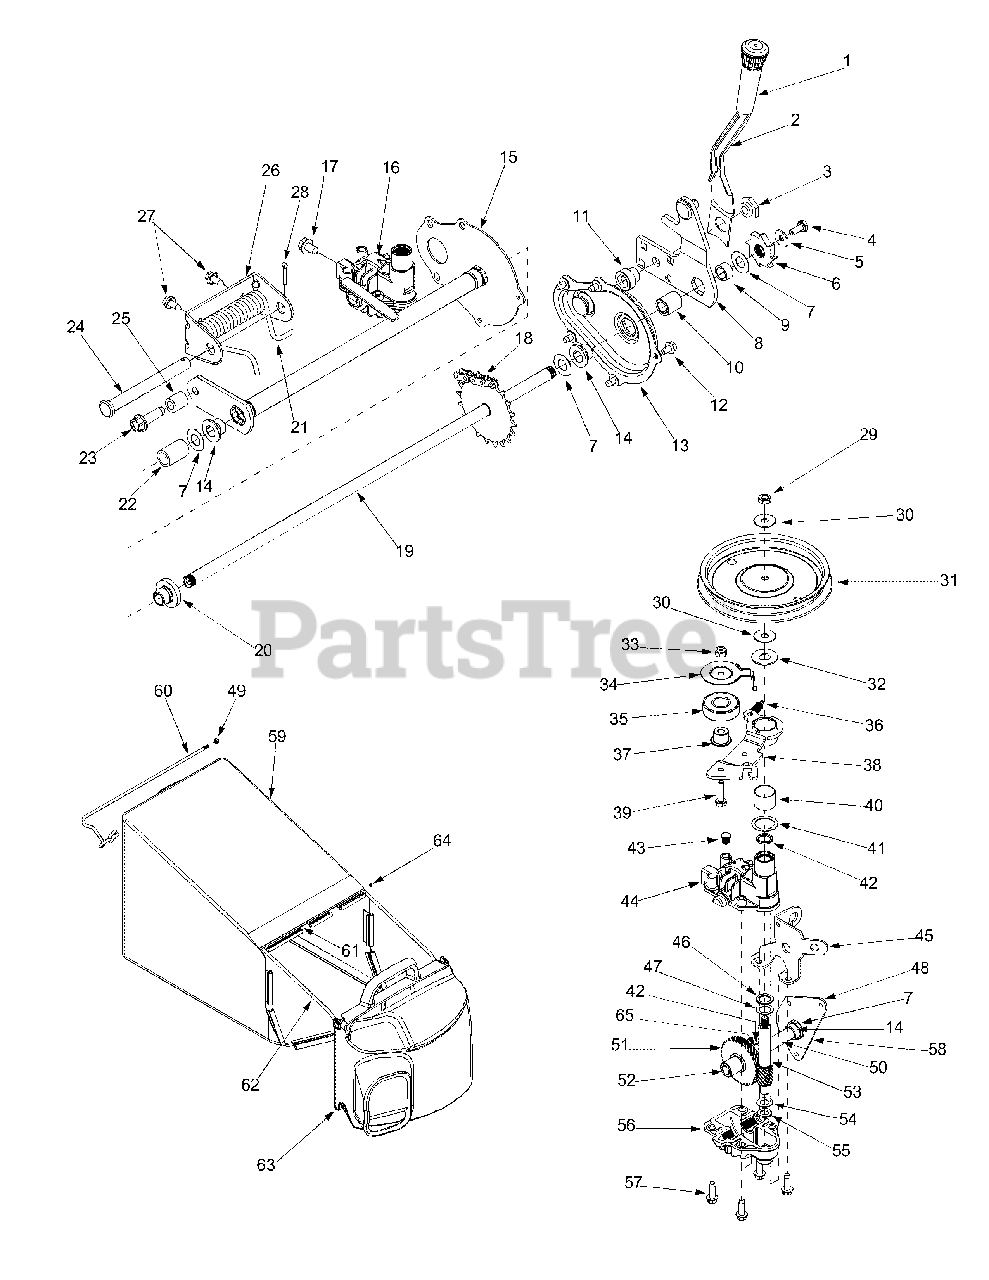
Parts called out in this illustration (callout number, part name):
2	Spring Lever
3	Shoulder Nut.825 x.165 Lg.
4	Cap Screw 1/4-20 x.620
5	Bell Washer.285 ID x.75 OD
6	Wheel Rachet
7	Flat Washer.508 ID x 1.0 OD
8	Pivot Arm Assembly
9	Spacer.510 ID x.70 OD
10	Sleeve Bearing.504 ID x.830 OD
11	Shoulder
12	Tap Screw 1/4-20 x.375
13	Chain Cover Assembly
14	Flange Bearing.506 ID x.590 Lg
15	Transmission Axle Assembly
16	Transmission Assembly
17	Hex Screw 5/16-18
18	Chain
19	Rear Axle Assembly
20	Flange Bearing.506 ID x.715 Lg
21	Torsion Spring
22	Spacer.550 ID x.750 OD
23	Screw 3/8-16 x.25
24	Clevis Pin.50 Dia x 4.82 Lg.
25	Spacer.385 ID x.624 OD
26	Height Adjustment Spring Bracket
27	Screw 1/4-20 x.625
28	Cotter Pin
29	Hex Jam Nut 5/16-24
30	Bell Washer.325 ID x.930 OD
31	Pulley
32	Flat Washer.510 ID x 1.120 OD
33	Hex Jam Nut 1/4-28
34	Belt Keeper
35	Bearing
36	Extension Spring
37	Flange Spacer
38	Idler Bracket Assembly
39	Hex Cap Screw 1/4-28 x 1.0
40	Bearing Sleeve
41	Flat Washer.885 ID x 1.45 OD
42	Oil Seal
44	Upper Housing Assembly
45	Cable Bracket
46	Bearing
47	Thrust Washer.504 ID x.70 OD
48	Pivot Bracket
49	Hex Nut 5/16-18
50	Output Shaft 6T
51	Gear 34T
52	Bearing
53	Pinion Shaft 10T
54	Thrust Washer 3/8 x.70
55	Thrust Washer.388 x.625
56	Lower Housing Assembly
57	Hex Screw 1/2-20 x.75
58	Shaft Assembly
59	Grass Bag
60	Support Rod w/ Rope Guide
61	Pivot Rod
62	Grass Bag Frame
63	Grass Bag Cover
64	Cap Nut
65	Bearing
